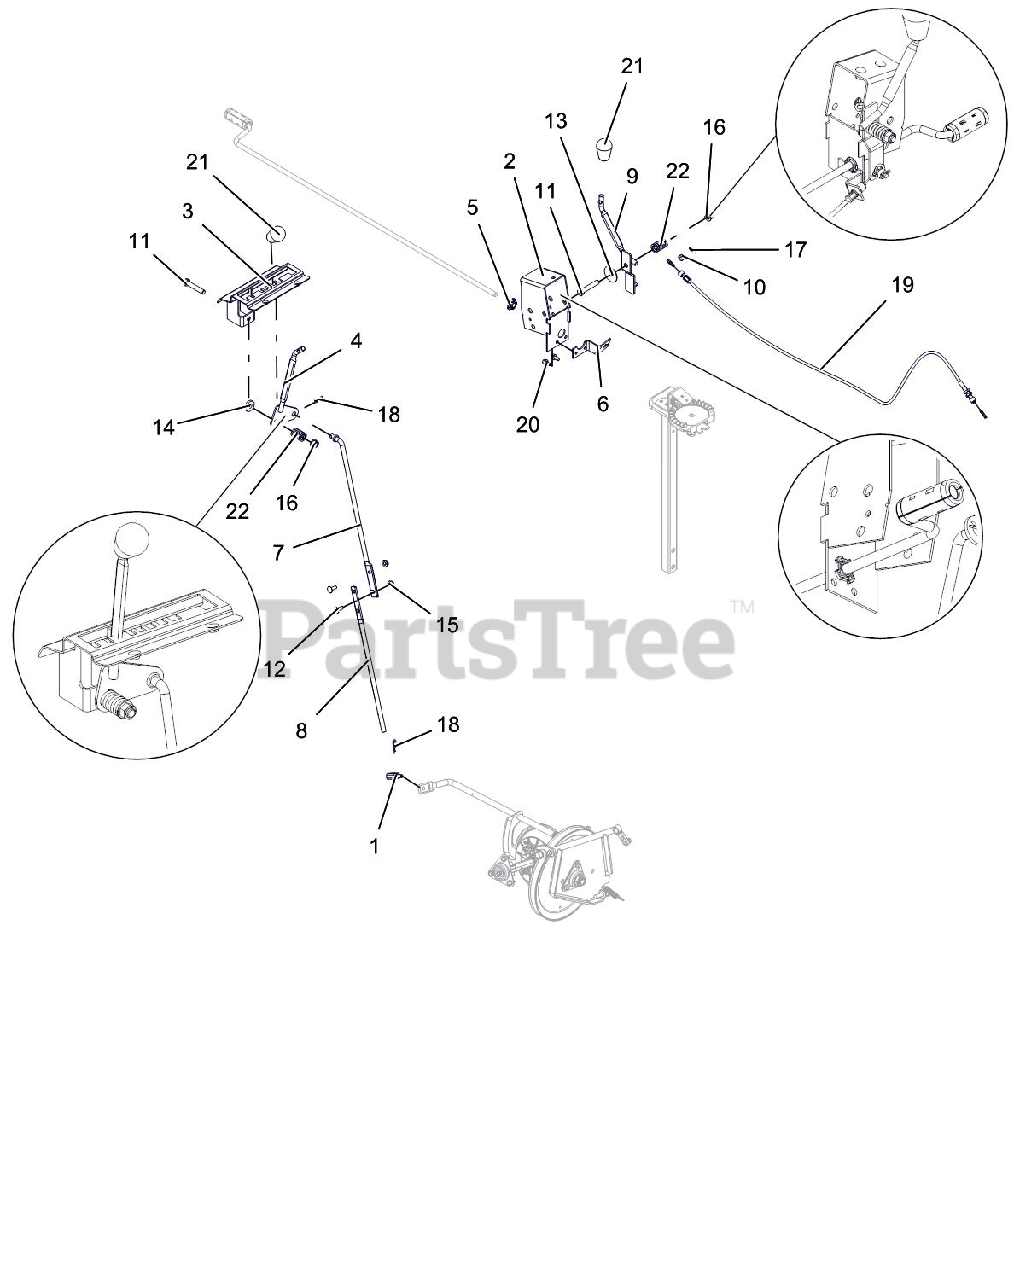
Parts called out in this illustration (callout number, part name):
1	PIVOT,SHIFT ROD .375-16(TRUNN)
2	WELDMENT, BRACKET INTERLOCK
3	WELDMENT, DETENT PLATE-COMPACT
4	LEVER, CONTROL-SHIFT(WELDMENT)
5	CRANK BUSHING, NYLON CHUTE BK
6	ANCHOR, DEFLECTOR CABLE
7	ROD, SHIFT - UPPER
8	ROD, SHIFT - LOWER(SMALL DASH)
9	WELDMENT,SM DASH DEFL CONTROL
10	BSHG-SLV .265X.500X.219
11	@BLT-HEX .38-16X2.00 GR5 YWZC
12	@BLT-RDHDSQNK .25-20X.75 G5YZ
13	WSHR-FL-STL .380X1.50X.062 YWZ
14	WSHR-FL-STL .406X1.00X.188 YWZ
15	@NUT-LK-CTR-FLG .25-20 YWZC
16	@NUT-LK-TOP-FLG .38-16 YWZC
17	PIN-HAIR INT .06X.18X.77
18	PIN-HAIR INT .08X.18X1.18 YWZC
19	CABLE, DEFLECTOR CAP SNO-TEK
20	SCR-TAP .25-20X.50 HWH TR YWZ
21	KNOB,SOFT TEARDROP,PUSH-ON BLK
22	SG-COMP .125X.781X1.250
